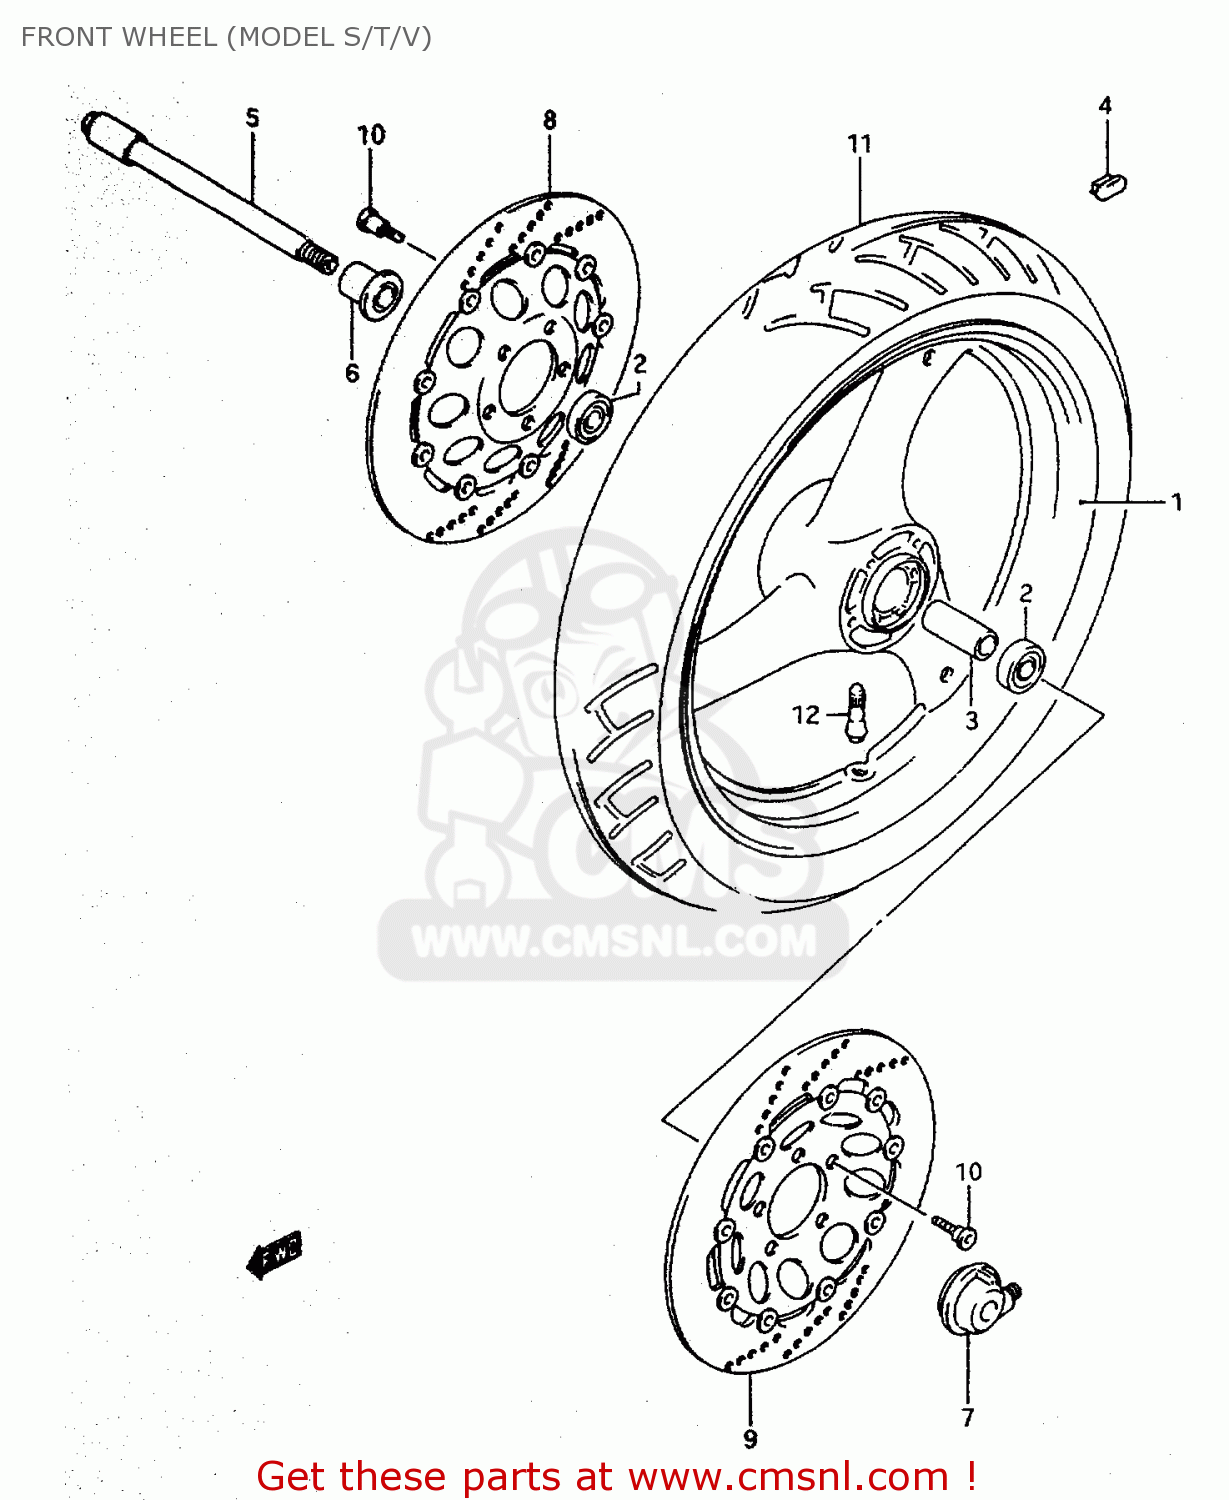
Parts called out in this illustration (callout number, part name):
1	WHEEL,FRONT
2	BEARING
3	SPACER(17.5X22.5X73)
4	BALANCER,WHEEL
5	AXLE,FR
6	SPACER,FR AXLE,R
7	BOX ASSY,SPEEDOMETER GEAR
8	DISC,FR BRAKE,R
9	DISC,FR BRAKE,L
10	BOLT 8X33
11	TIRE,FRONT 120/70 ZR17
12	VALVE ASSEMBLY,WHEEL,TR412
